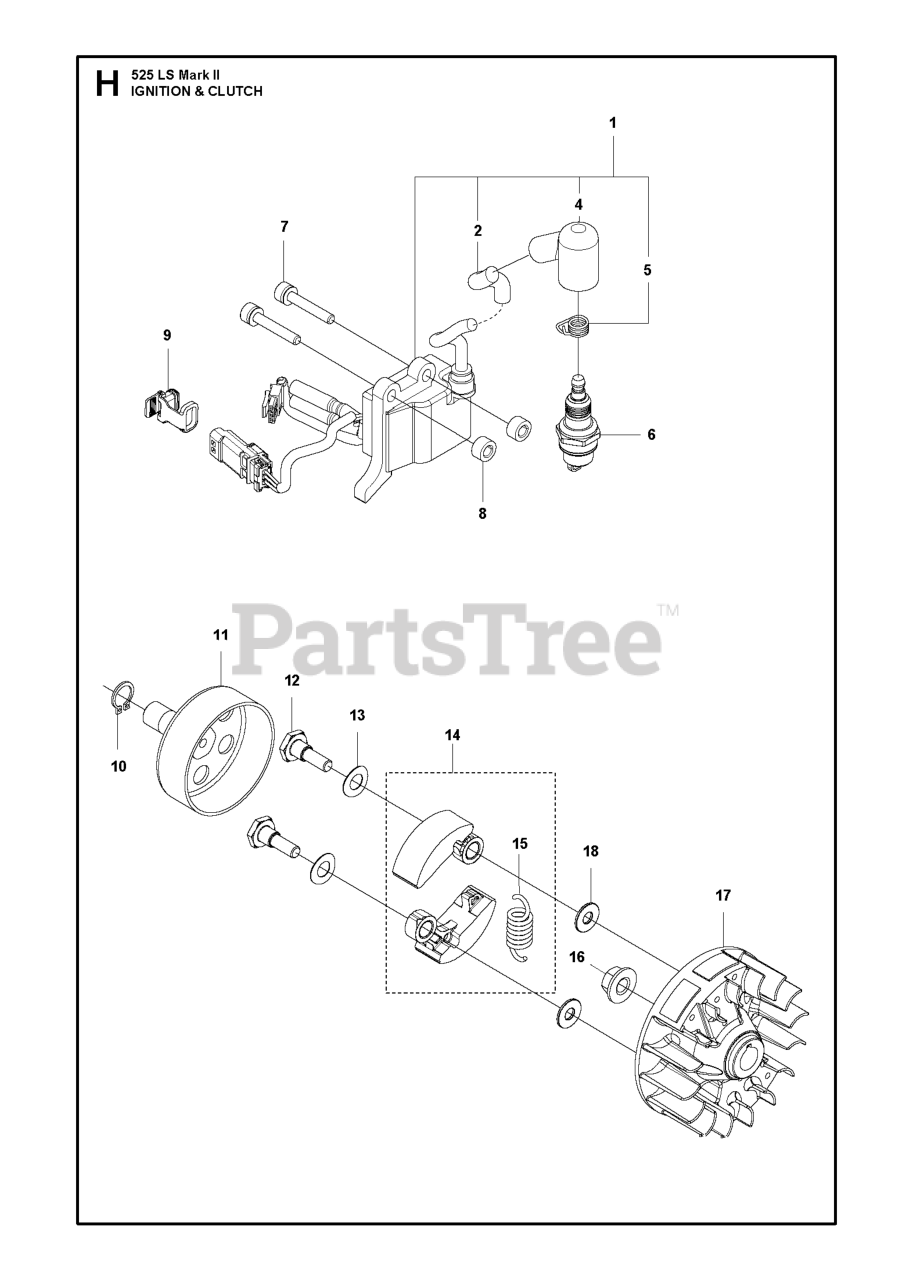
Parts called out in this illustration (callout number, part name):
1	IGNITION COIL ASSY
4	SPARK PLUG CAP
5	SPRING IGNITION COIL
6	SPARK PLUG HQT-2 RESISTOR
7	BOLT M4 X 25
8	SPACER
11	CLUTCH DRUM
14	CLUTCH ASSY
15	CLUTCH SPRING
16	NUT
